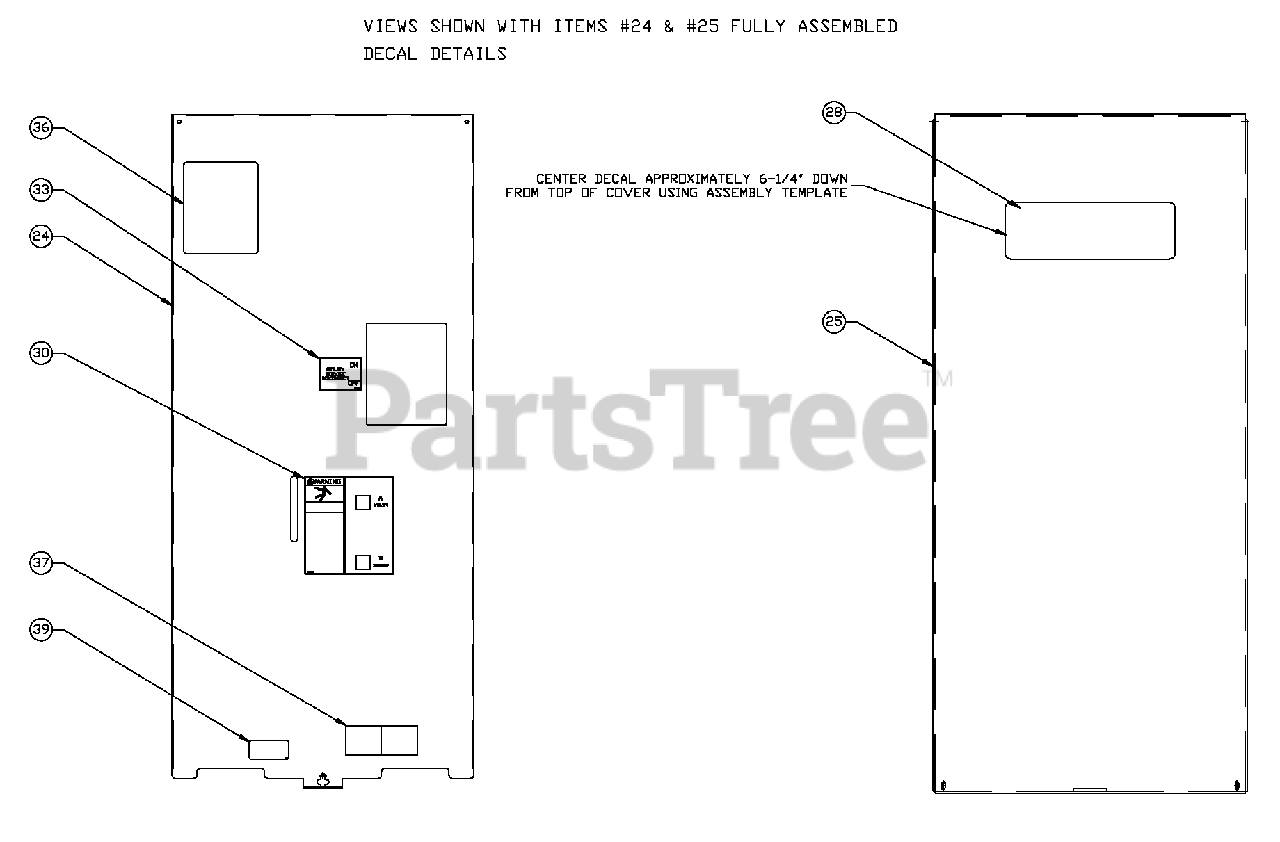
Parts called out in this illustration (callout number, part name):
24	COVER INSIDE 400A SE ENC
25	COVER 400A SE ENCLOSURE
28	DECAL, TRANSFER SWITCH RTS SE
29	DECAL, DATA XFER SW SD 400A
33	DECAL, UTILITY DISCONNECT
36	DECAL, TEST SEQUENCE
37	DECAL, TERMINAL SHOCK HZD BI
